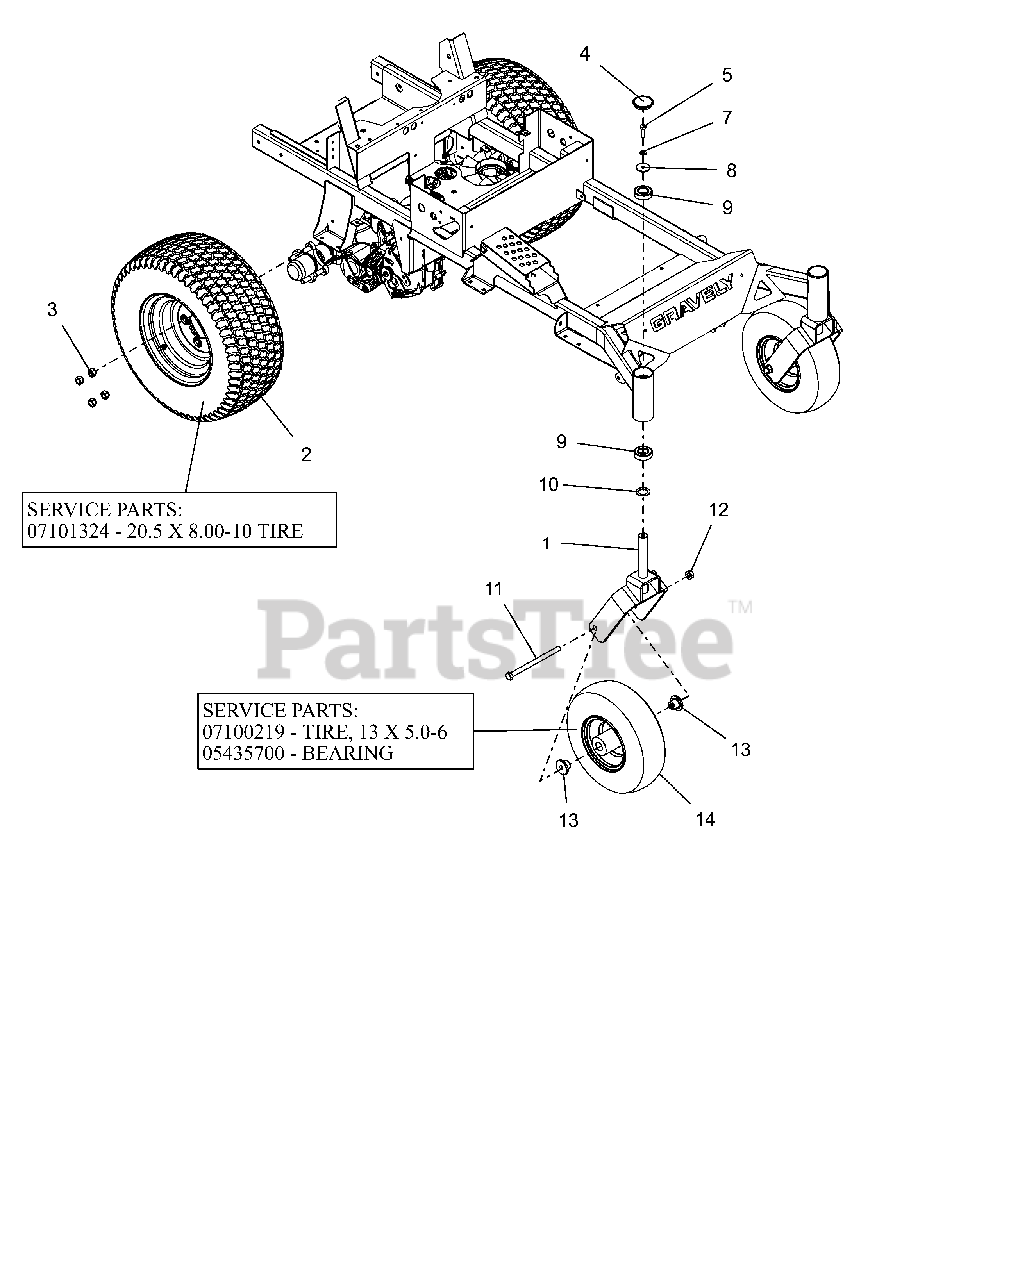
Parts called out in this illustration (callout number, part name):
1	WLDMT, COMPACT PRO CASTER FORK
2	ASM, WHL/TIRE 20.5X8-10
2	TIRE, 20.5 X 8.00-10
3	WHEEL NUT .500-20 YZ
4	CAP, DUST
5	BLT, HEX .38-16X1.25 G5 ZCC
7	WSHR, LK-HVY .375X.115 ZCC
8	WSHR, FLT .380X1.50X.125 ZCC
9	BRG,BALL 1.00X2.00X.563(1641)
10	WSHR-HRD-THRS 1.007X1.542X.062
11	BLT, HEX .50-13X7.50 G5 ZCC
12	NUT-LK-CTR-FLG .500-13 GG ZCC
13	SPACER, FRONT WHEEL
14	ASM, WHL/TIRE 13X5.00-6
14	TIRE, 13X5.00-6
14	BRG, 25MM ID X 52MM OD X 15MM
